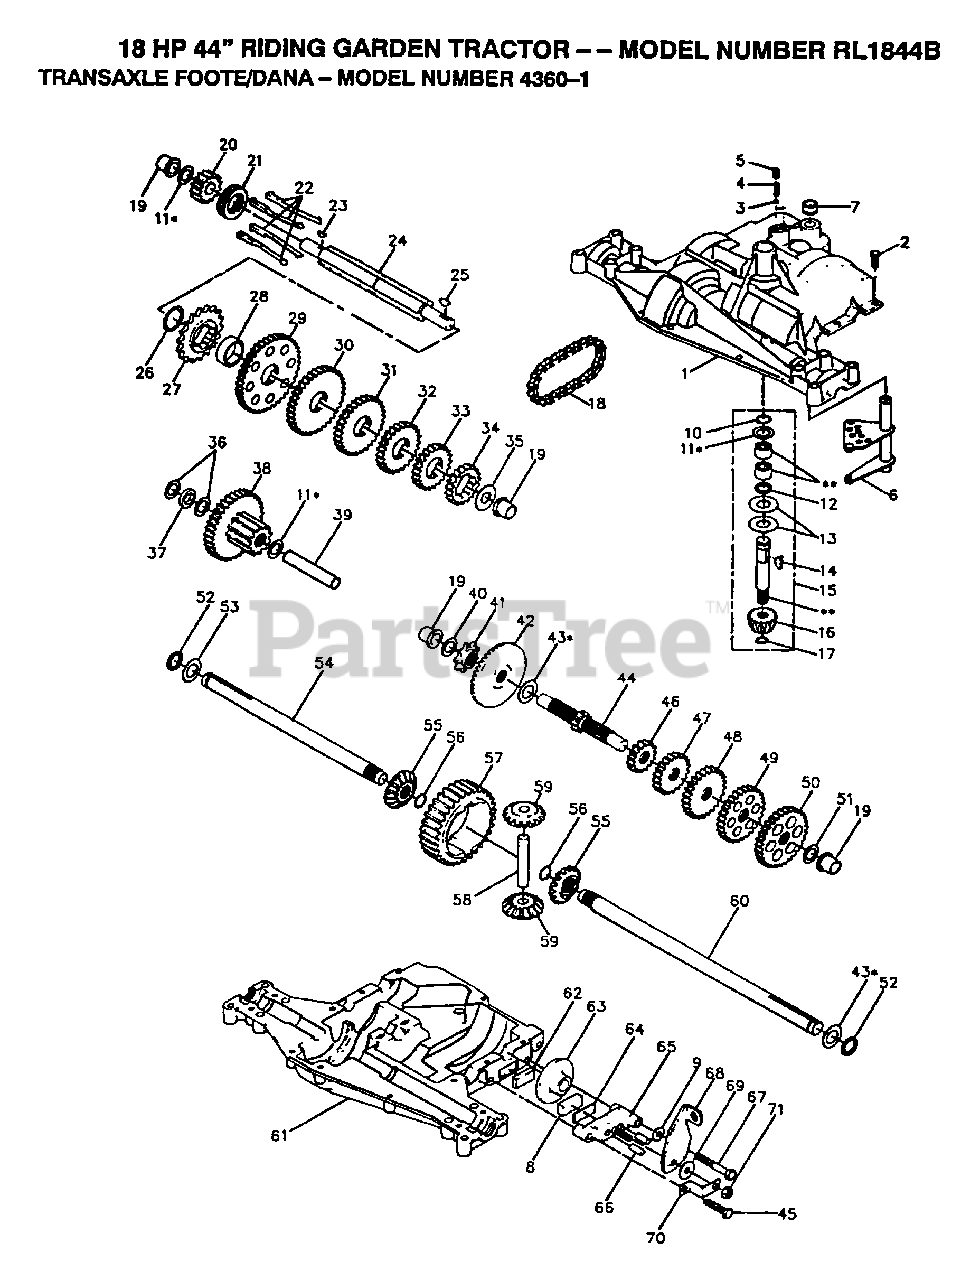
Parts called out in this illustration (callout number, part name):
1	HOUSING UPPER
3	"DETENT, BALL(68003)"
4	"SPRING, DETENT LT"
5	"SCREW, SET LT"
8	PUCK T
9	WASHER T
10	RETAINING RING LT
11	WASHER
12	O-RING T
13	WASHER T
14	WOODRUFF KEY
17	"RING,RETAINING LT"
18	"CHAIN,24 PTCH LT"
19	BEARING.FLNG.5510
20	"GEAR, SPUR LT"
22	KEY T
24	SHAFT INTERMEDIAT
25	WOODRUFF KEY
26	"RING,RETAINING LT"
27	SPROCKET 18T T
28	SPACER YT
29	GEAR SPUR 40T
31	GEAR SPUR 30T
32	GEAR 25T LT
33	GEAR SPUR 22 TT
35	"WASHER, PLAIN LT"
36	WASHER 025
37	SPACER
38	GEAR COMB LT
40	WASHER
41	SPROCKET 9T LT
43	WASHER LT
45	"SCREW, TAPPING LT"
47	GEAR SPUR 20T
48	"GEAR, SPUR 25T LT"
49	GEAR 28T T
50	"GEAR, SPUR 31T LT"
51	WASHER 060
53	WASHER 062
55	GEAR LT
56	"RING,RETAINING LT"
58	SHAFT T
59	"GEAR,MITER 15T YT"
61	"HOUSING, LOWER"
62	PUCK T
63	BRAKE DISC. T
64	SPACER LT
66	PIN T
67	SCREW T
68	LEVER ACTUATOR
69	WASHER LT
71	NUT.LOCK.5/16-24
